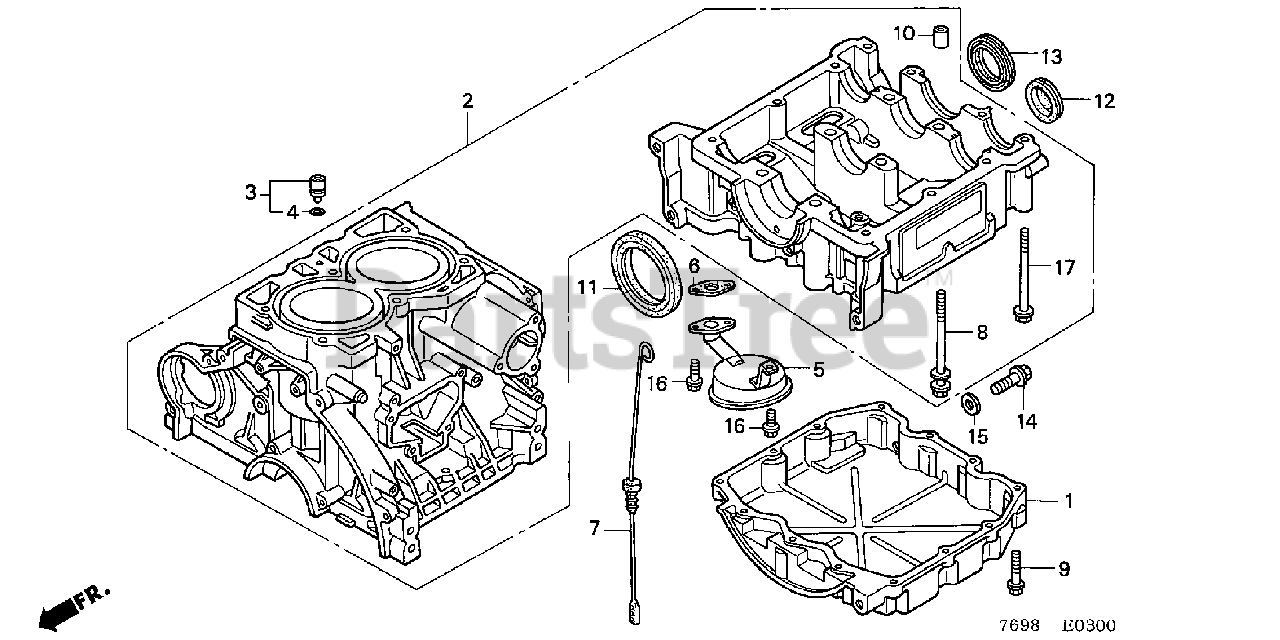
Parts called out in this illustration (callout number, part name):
2	BLOCK ASSY., CYLINDER
3	ORIFICE ASSY., OIL PASSAGE
4	O-RING (4.8X1.9)
5	STRAINER, OIL
6	GASKET, OIL STRAINER
7	DIPSTICK, OIL
8	BOLT-WASHER (10X105)
9	BOLT, FLANGE (6X28)
10	PIN, DOWEL (13X20)
11	OIL SEAL (65X88X12)
12	PLUG, SEALING (42X7)
13	OIL SEAL (35X50X8)
14	BOLT, DRAIN PLUG (12MM)
15	WASHER, DRAIN PLUG (12MM)
16	BOLT, FLANGE (6X18)
17	BOLT, FLANGE (8X85)
